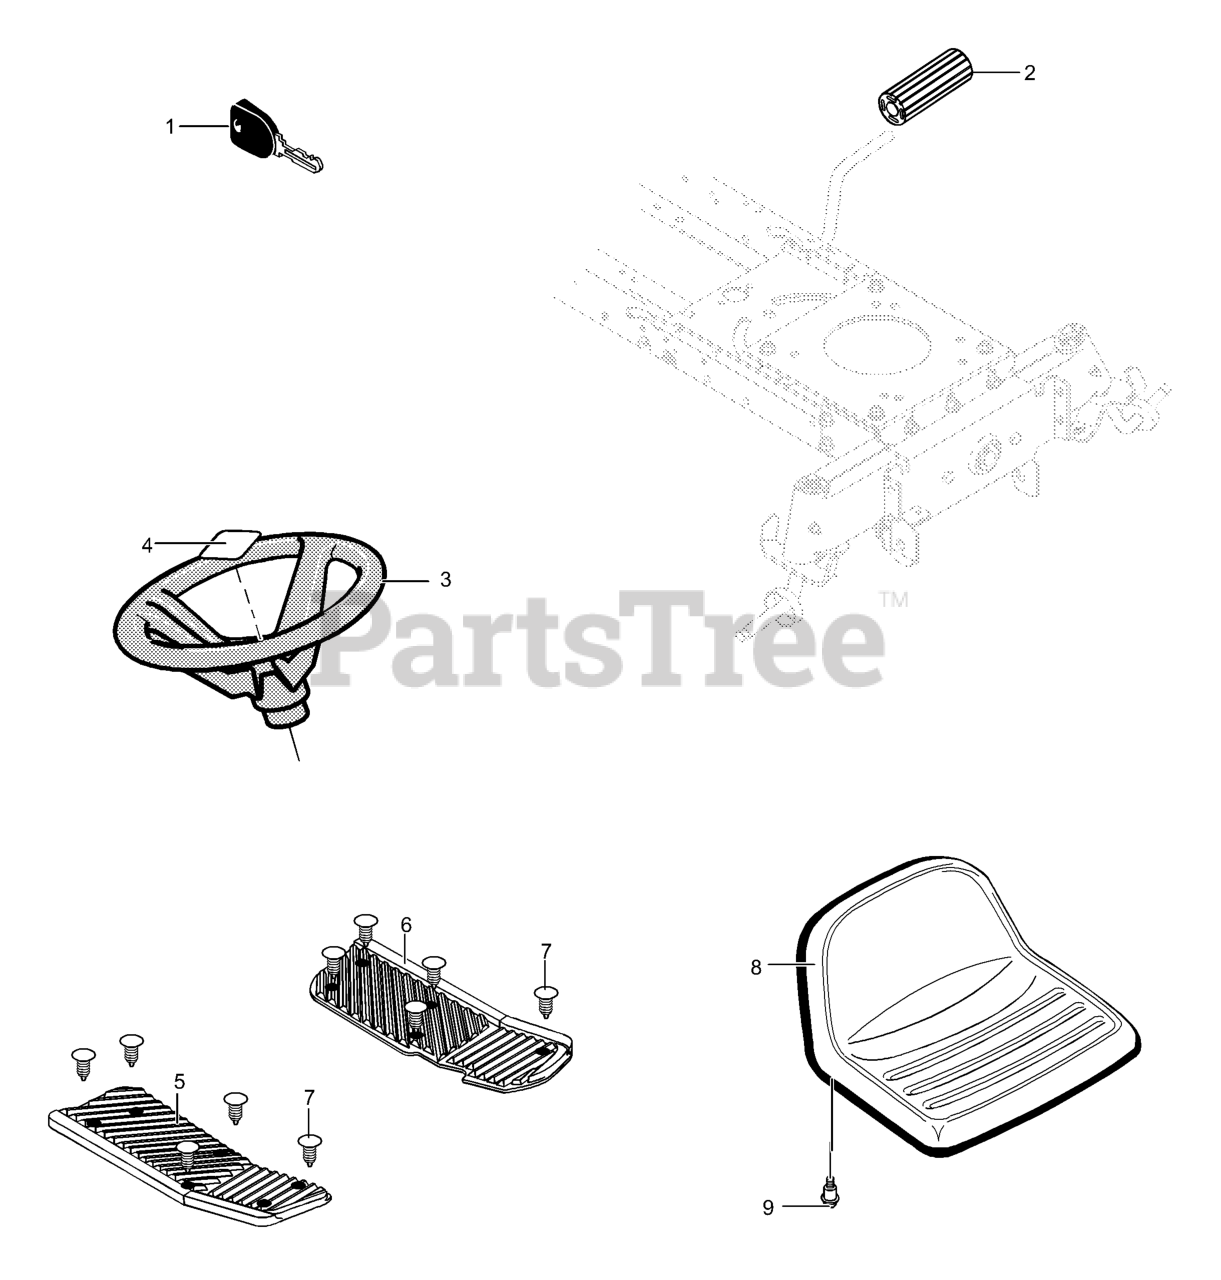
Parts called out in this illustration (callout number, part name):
1	Ignition Key
2	Cover, Pedal Brake/Clutch
3	Steering Wheel
4	Insert, 4-Spoke
5	Footrest Pad RH
6	Footrest Pad LH
7	Ratchet Fastener
9	Shoulder Bolt 5/16-18
